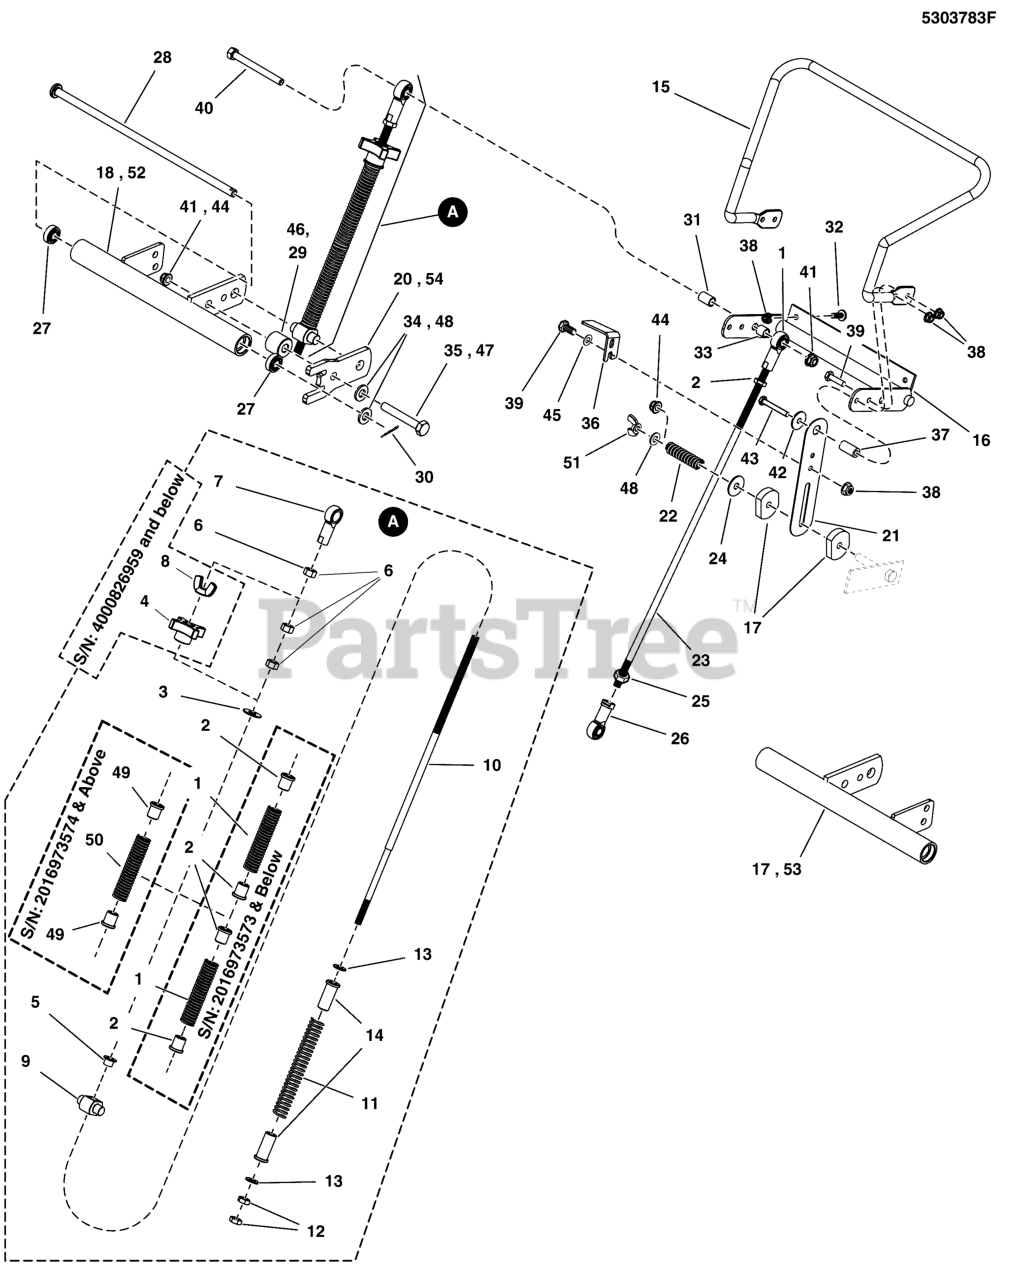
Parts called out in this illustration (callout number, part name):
1	SPRING-COMP, .615ID X 4.00LG X .080WR
2	BUSHING, .38 X .75 X .75, PLASTIC
3	WASHER, 3/8 USS
4	KNOB, 4 ARM, 3/8-24
5	BUSHING, .38ID X .47 OD X .38L, FL
6	NUT, 3/8-24 HEX
7	BALL JOINT, 3/8-24 FEMALE
8	WING NUT, 3/8-24, CZ
9	TRUNION, 1/2" POSTS, STAINLESS
10	ROD, 3/8-24 X 16.50,STEP DOWN TO 5/16
11	SPRING, COMP, .60 ID X 5.50 LG, .080W
12	NUT, 5/16-18 HEX
13	WASHER, 5/16" SAE
14	BUSHING, .31IDX.60OD X 1.50L, FL (.75OD)
15	BAR, SPEED CONTROL - BLK
17	PAD, T-712 FRICTION MATERIAL
18	WELD, CENTER PIVOT HUB, RH - WALK - BLK
19	WELD, CENTER PIVOT HUB, LH - WALK - BLK
20	TAB, CONTROL PIVOT - BLK
21	PLATE, FRICTION CONTROL, SS
22	SPRING, COMP, .40 X .60 X 2.25, BLACK
23	ROD, 3/8-24, 19.00, LH-RH CZ
24	WASHER, 5/16 FENDER
25	NUT, 3/8-24 HEX, LH
26	BALL JOINT, 3/8-24 FEMALE, LH
27	BEARING, .375" ID X .875" OD X .341" THK
28	ROD, 3/8 X 12, HEADED - CZ
29	SPACER, .39 X 1.00 X .88, CZ
30	PIN, COTTER, 1/8 X 1-1/4
31	SPACER, .38 X .50 X .75
32	SCREW-TRUSS HD TORX DR 1/4-20X0.750 T27
33	SPACER, .38 X .50 X .50
34	WASHER, 3/8 SAE
35	BOLT, 3/8-16 X 2, GD5, CZ
36	BRACKET, SWITCH ENGAGEMENT - BLK
37	SPACER, .26 X .50 X 1.00
38	NUT, 1/4-20 HEX NYLOCK FLANGE
39	BOLT-1/4-20 X 3/4 GD5 CZ
40	BOLT, 3/8-16 X 3" GD5 CZ
41	NUT, 3/8-16 HEX NYLOCK FLANGE
42	WASHER, 1/4 FENDER
43	BOLT, 1/4-20 X 2", GD5
44	NUT, 5/16-18 HEX NYLOCK FLANGE
45	WASHER, 1/4 SAE
46	SPACER, .33 X 1.00 X .88, CZ
47	BOLT, 5/16-18 X 2 GD5
48	WASHER, 5/16" SAE
49	FLANGED BUSHING, 3/8IDX.63ODX.8125FL
50	SPRING,COMP,.645IDX8.00LGX.080WR,BLK E-C
51	NUT, Wing, 5/16-18
52	WELD, W35 CONTROL PIVOT, RH - BLK
53	WELD, W35 CONTROL PIVOT, LH - BLK
54	TAB, PIVOT, W35 - BLK
